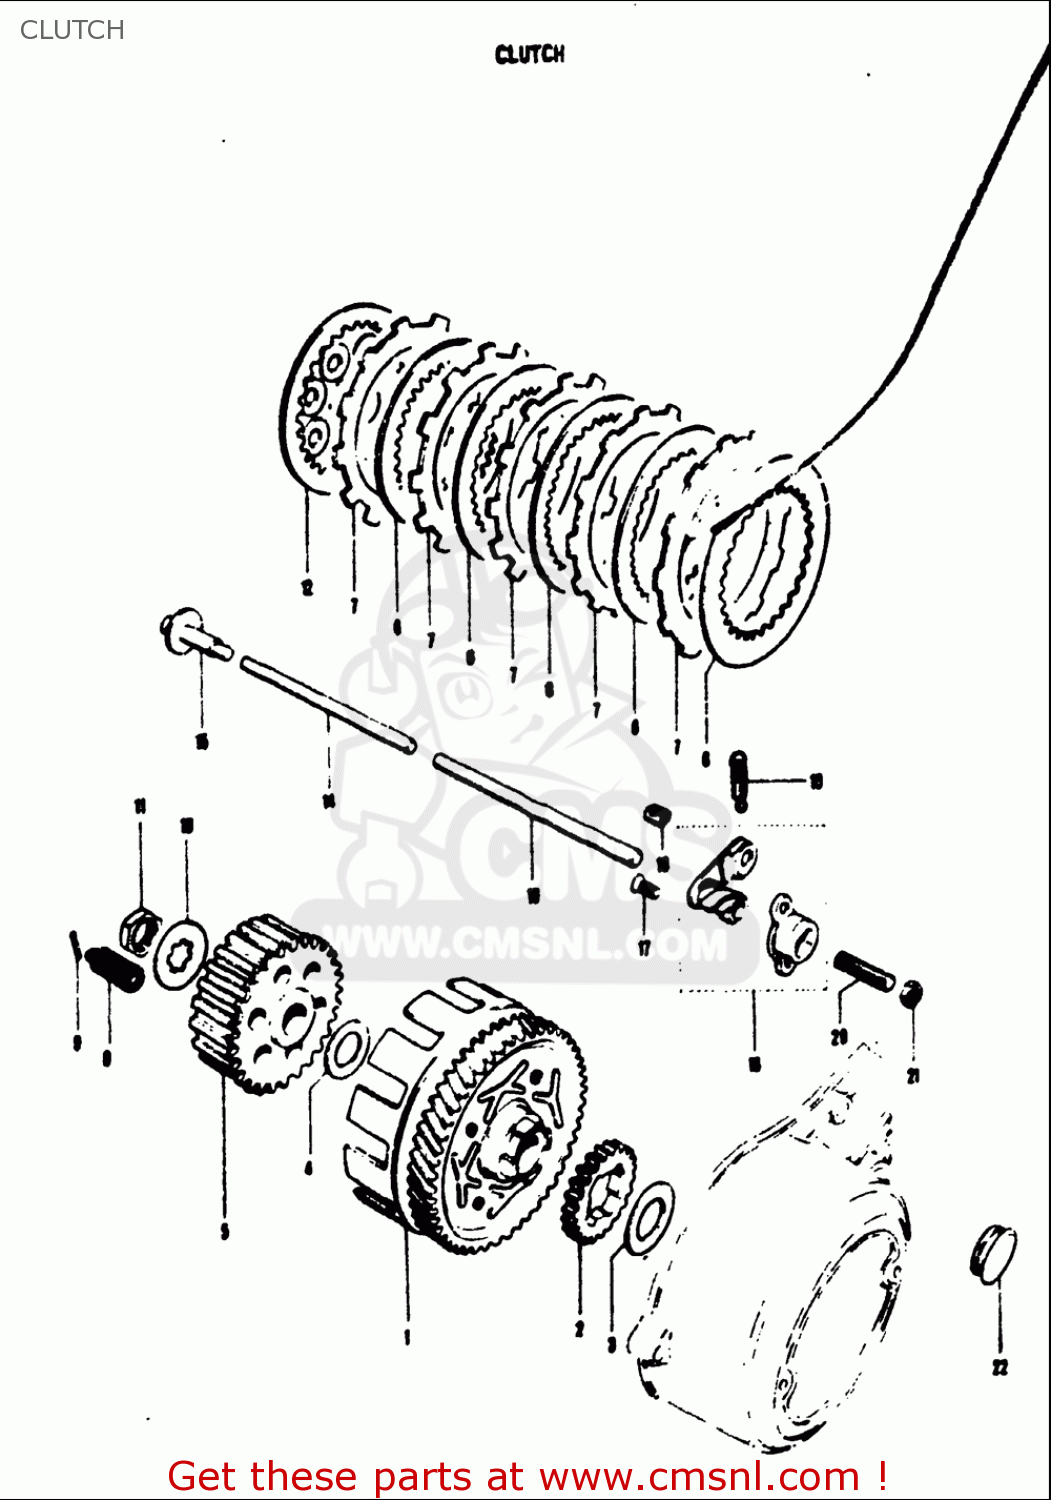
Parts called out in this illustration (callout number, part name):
3	WASHER
4	WASHER
6	PLATE,CLUTCH DRIVEN (NAS)
7	PLATE,CLUTCH DRIVE (NAS)
8	SPRING
9	PIN(2.5X19.8)
10	WASHER,LOCK
11	NUT
14	ROD,CLUTCH PUSH
15	ROD,CLUTCH RELEASE
16	SCREW ASSY,CLUTCH RELEASE
18	PIECE,RELEASE ARM END
19	SPRING
20	SCREW(6X25)
21	NUT
22	CAP(OD:24)
